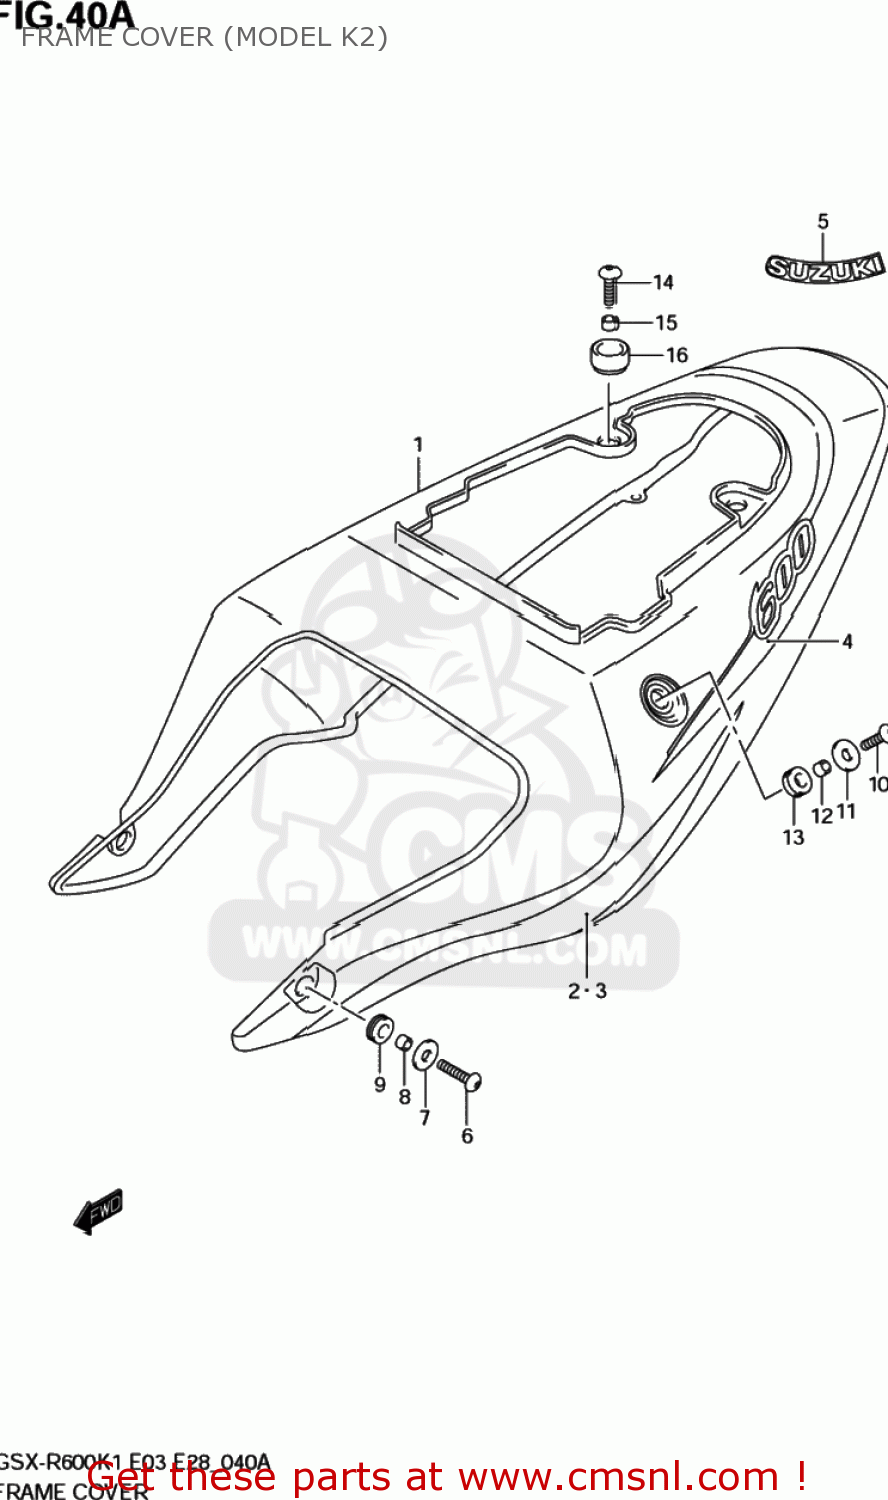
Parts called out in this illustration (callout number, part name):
1	COVER ASSY,FRAME(BLUE)
2	TAPE,FRAME COVER,R(BLUE)
3	TAPE,FRAME COVER,L(BLUE)
4	TAPE,FRAME COVER
5	EMBLEM,SUZUKI
6	SCREW(6X30)
7	WASHER(6.5X20X2)
8	SPACER(6.5X10X7)
9	CUSHION,FRAME COVER FR
10	SCREW(6X25)
11	WASHER(6.5X20X2)
12	SPACER(6.5X10X7)
13	CUSHION,FRAME COVER SIDE
14	SCREW(6X25)
15	SPACER(6.5X10X9.4)
16	CUSHION
